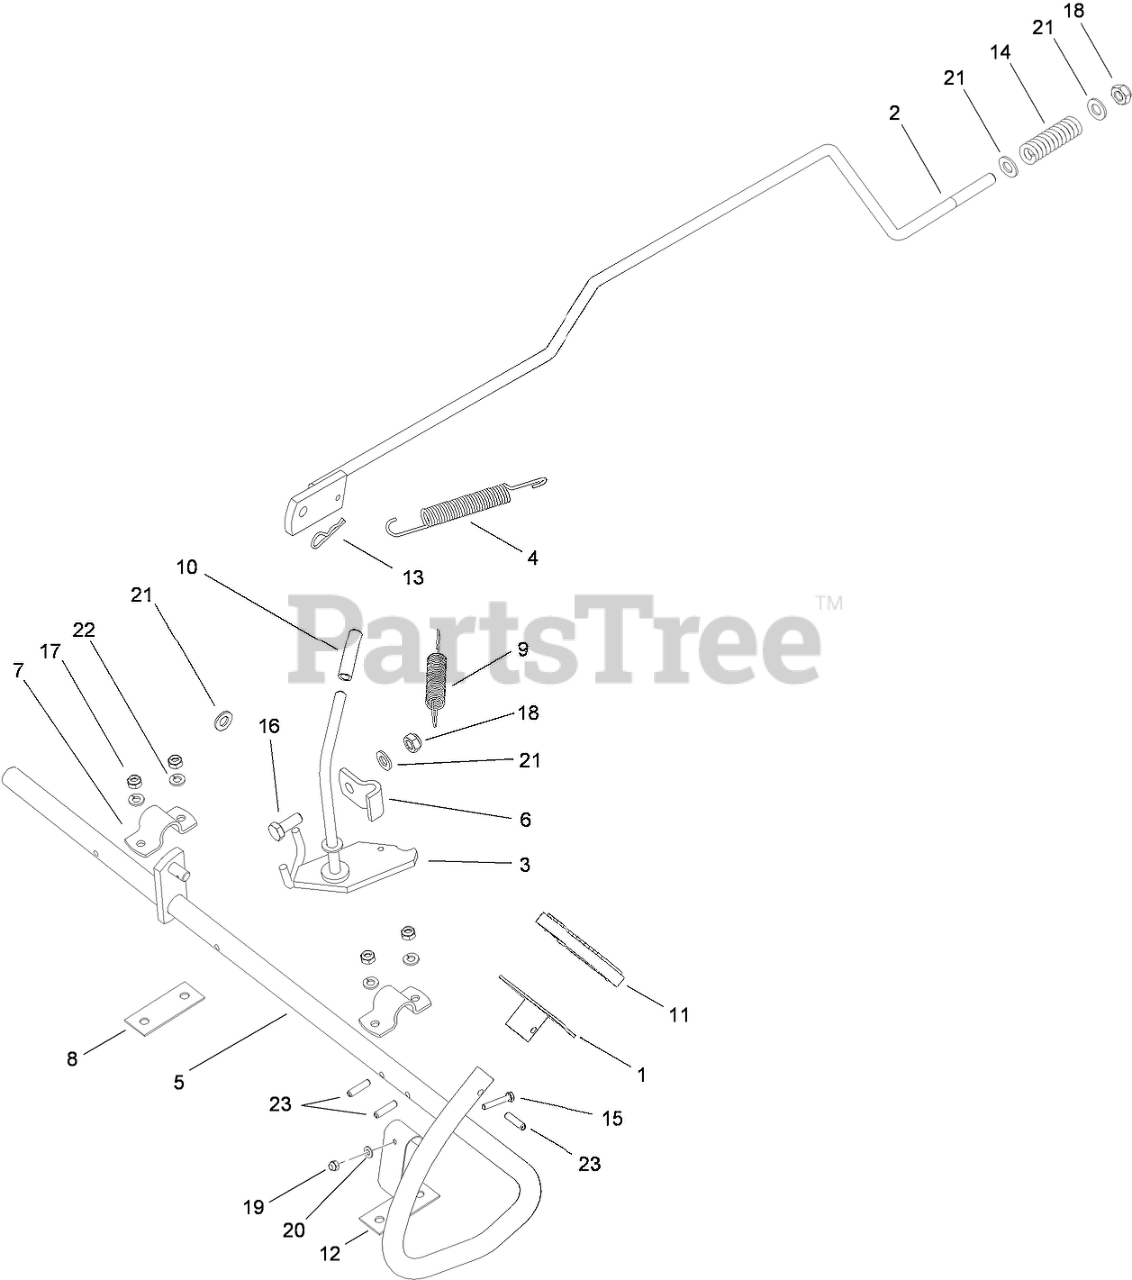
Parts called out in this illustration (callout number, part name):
1	PEDAL-PAD,
2	ROD-BRAKE LINKAGE
3	LEVER-PARKING BRAKE
4	SPRING
5	PEDAL-TRAVEL, BRAKE
6	CLAMP-LEVER, PARKING BRAKE
8	SPACER
9	SPRING-BRAKE, HAND
11	PAD-PEDAL
12	BRACKET-PARKING BRAKE
13	PIN-COTTER
14	SPRING-BRAKE
15	SCREW-HEX
16	SCREW-HH
17	NUT-LOCK
18	NUT-LOCK, NI
19	NUT-HEX
20	Washer
21	WASHER-PLAIN
22	WASHER-SPRING
23	PIN-SPRING
